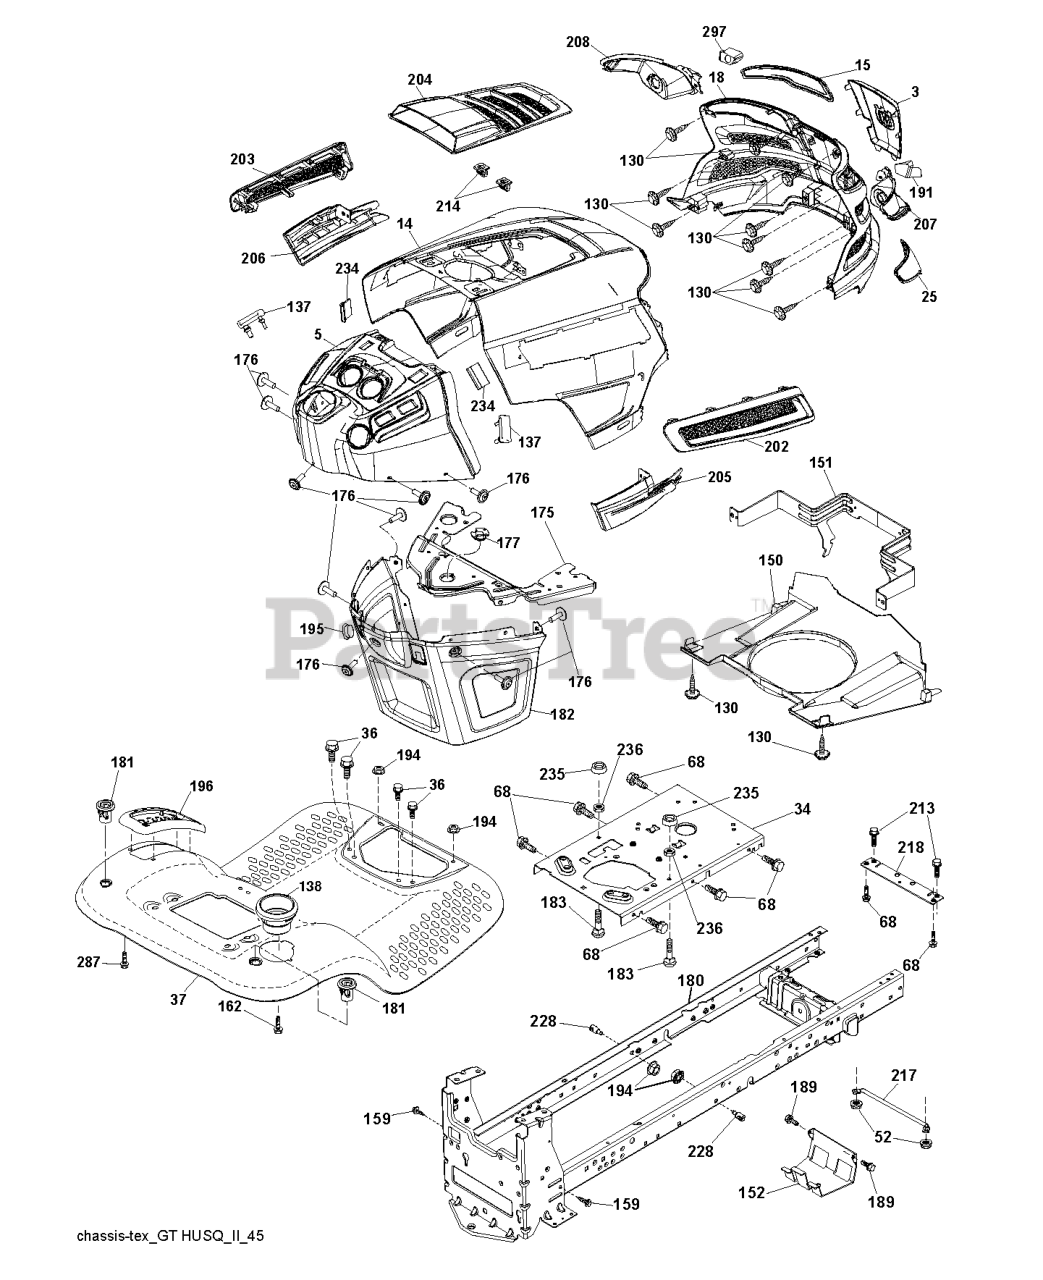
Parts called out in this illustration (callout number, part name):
3	APPLIQUE.SUBASM.GT.HUSQ.II
5	RP.DASH.UPP.GT2.SM.MC.CHOKE
14	HOOD.ASM.HUSQVARNA.GT.TEX.ORAN
15	LENS.HEADLIGHT.LH.GTII.2011
18	GRILLE.SUBSTRATE.2011.
25	LENS.HEADLIGHT.RH.GTII.2011
34	PLATE.ENGINE.WELDED.CHASSIS
36	SCREW 5/16"
37	FENDER.TLT.PDL.CNTRL.W/CPH.ORG
52	LOCKNUT
68	Screw 5/16-18 x 1/2 Hex, Self Tapping 5/16-18 x 1/2
130	SCREW.#10 X 0.750.BOS
137	BUMPER DASH
138	HOLDER.CUP.LT.GREY
150	AIR DUCT.GTV2(1.66"RING HEIGHT
151	BRACKET.PIVOT.HOOD.GT.HUSQ.II
152	SHIELD.BROWNING.W/TEX
159	SCREW, 3/8-16X3/4
162	SCREW.HI-LO.CONSOLE
175	PLATE.CROSSMEMBER.HUSQ
176	SCREW.#10-24X5/8.RN.QU
177	BUSHING, STEERING
180	CHASSIS
181	BUSHING.MNT.FEND.CRGO.TEX.49
182	DASH.LOWER.COMMON.12V.ADAPTOR
183	BOLT.5/16-18X1-1/4 FULL THD
189	SCREW
191	INSERT.REFLECTIVE.RH.HUSQ.GTII
194	NUT LOCK HEX FLANGE 5/16-18
195	PLUG.HOLE.DASH.LOWER.12V.BLK
196	DECKLFT.CONSOL FULL ASSM GREY
202	VENT.SIDE.RH.GT.HUSQ.II.
203	VENT.SIDE.LH.GT.HUSQ.II.498
204	VENT.TOP.HUSQ.GT2
205	SIDE.TRIM.RH.GT.HUSQ.II
206	SIDE.TRIM.LH.GT.HUSQ.II.GRAY
207	BEZEL LIGHT.RH.GT.II.MYLAR
208	BEZEL LIGHT.LH.GT.II.MYLAR
213	BOLT
214	CLIP.RETAINER.TINNER.
217	ROD.PIVOT.HOOD
218	X-PIECE.HOOD.STOP.NON/
228	STUD.FASTNER.W/ANTI-ROTATE
234	BUMPER.HOOD.TEX.HUSQVARNA
235	SPACER FENDER
236	NUT.CENTERLOCK.5/16-
287	SCREW 1/4X20
297	INSERT.REFLECTIVE.LH.HUSQ.GTII
